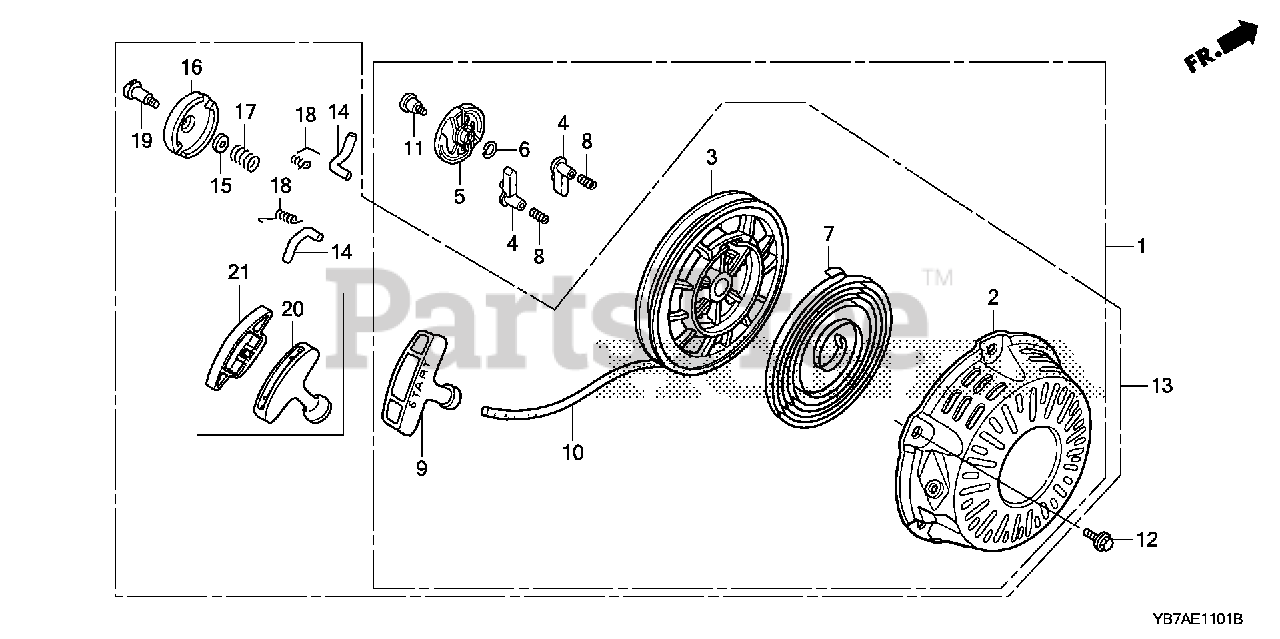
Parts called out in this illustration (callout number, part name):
2	CASE, RECOIL STARTER *R280* (POWER RED)
3	REEL, RECOIL STARTER
7	SPRING, RECOIL STARTER
10	ROPE, RECOIL STARTER
12	BOLT, FLANGE (6X10)
12	BOLT, FLANGE (6X8)
13	STARTER ASSY., RECOIL *R280* (COO)(FOR U.S.A.) (POWER RED)
14	RATCHET, STARTER
15	PLATE, FRICTION
16	GUIDE, RATCHET
17	SPRING, FRICTION
18	SPRING, RETURN
19	SCREW, SETTING
20	KNOB, RECOIL STARTER (COO)(FOR U.S.A.)
21	KNOB, REINFORCEMENT
